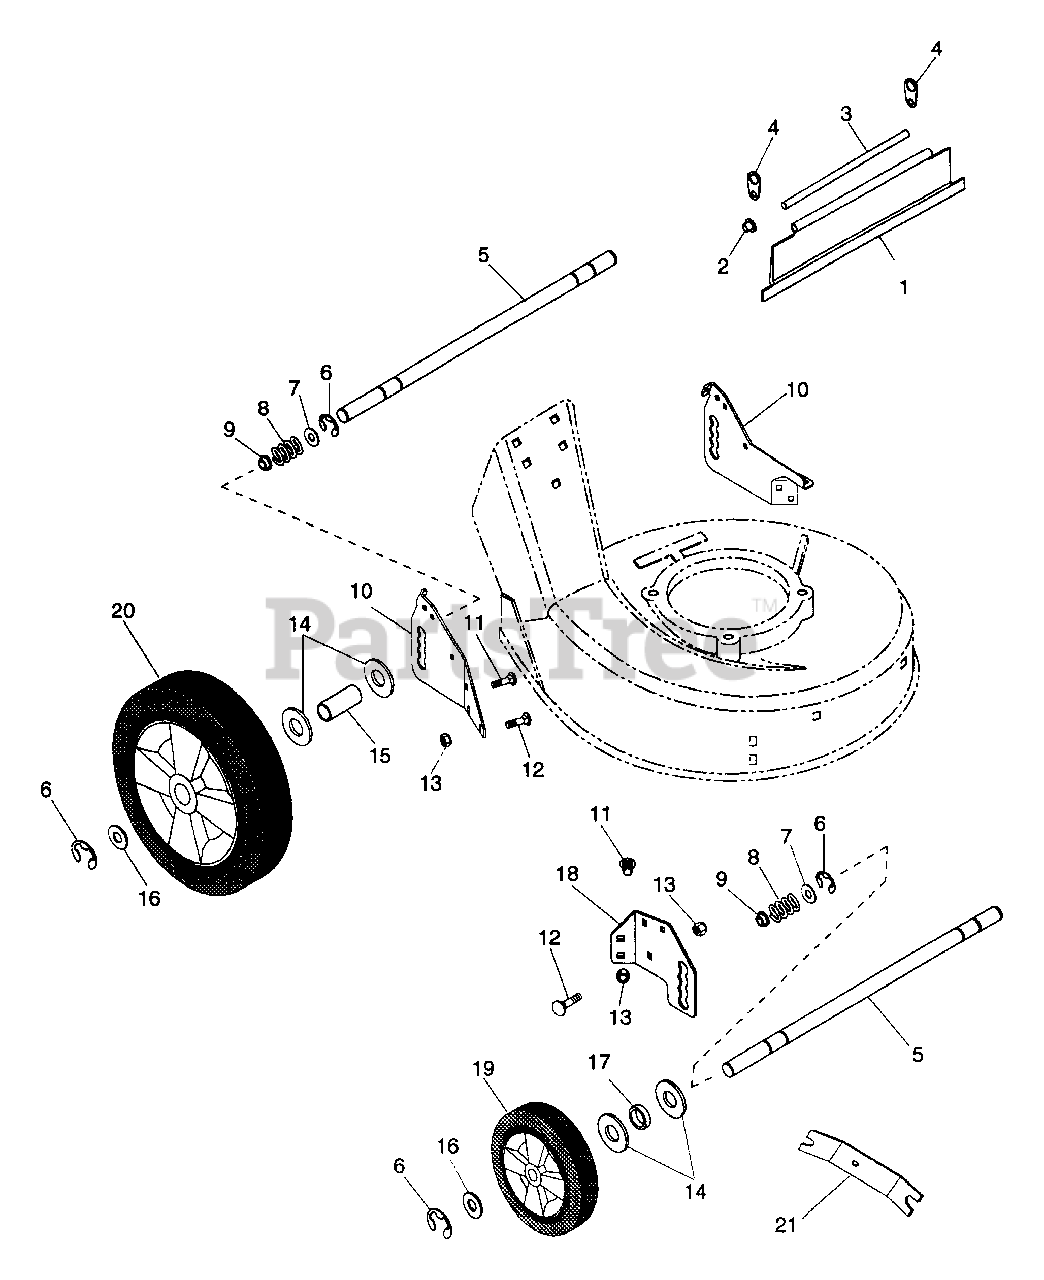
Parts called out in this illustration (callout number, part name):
1	REAR PROTECTIVE GUARD
2	NUT-PUSH .312 DIA. PAL
6	RG-RTNG-EXT .500X.042 (E)
7	WSHR-FL-STL .505X.875X.024 PL
8	SG-COMP .62X.68X1.75
9	BSHG-FLG.500X.750X.750X1.000BR
10	LH REAR QUADRANT
10	RH REAR QUADRANT
11	BLT-RDHDSQSHNK .31-18X.50 YZ
12	BLT-RDHDSQNK .312-18X.62SHTPL
13	NUT-FLG. .312-18 PL
14	WSHR-FL-STL .531X1.062X.095 PL
15	SPACER TUBE,PUSH LH
15	SPACER TUBE PUSH RH
16	WSHR-FL-STL .505X.880X.072 PL
17	BSHG, SPCR.500X.750X.321 PM
18	REPLACED BY 011711 AND 011712
18	RH FRONT QUADRANT
18	LH FRONT QUADRANT
19	TIRE 7X1.50
20	TIRE 10X1.75
21	AXLE TOOL
